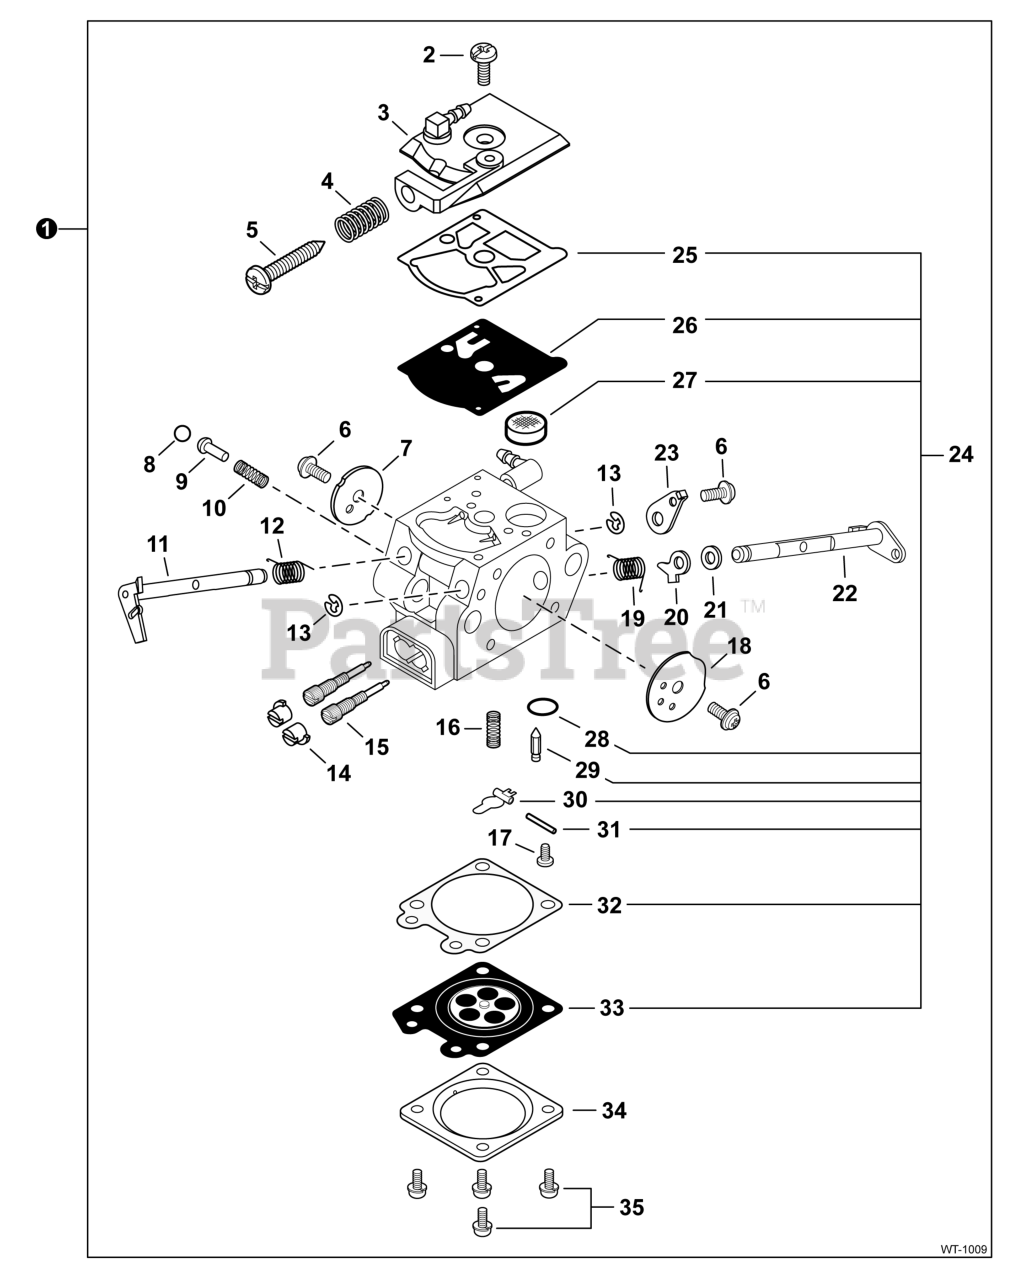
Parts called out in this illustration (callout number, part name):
1	CARBURETOR - WT-1009
3	COVER ASSY, PUMP
4	SPRING, IDLE ADJUST
5	SCREW, IDLE ADJUST
7	VALVE, THROTTLE
9	PISTON ASSY
10	SPRING, START VALVE
11	SHAFT ASSY, THROTTLE
12	SPRING, THROTTLE RETURN
14	CAP, LIMITER
15	NEEDLE LOW SPEED
16	SPRING, METERING LEVER
17	SCREW, METERING LEVER PIN
18	VALVE, CHOKE
20	LEVER, FAST IDLE
22	SHAFT ASSY, CHOKE
23	LEVER, THROTTLE
24	REPAIR KIT, CARBURETOR
25	GASKET, FUEL PUMP
26	DIAPHRAGM, PUMP
27	SCREEN, FUEL INLET
28	PLUG, WELCH
29	VALVE, INLET NEEDLE
30	LEVER, METERING
31	PIN, METERING LEVER
32	GASKET, METERING DIAPHRAGM
33	DIAPHRAGM, METERING
34	COVER, METERING DIAPHRAGM
